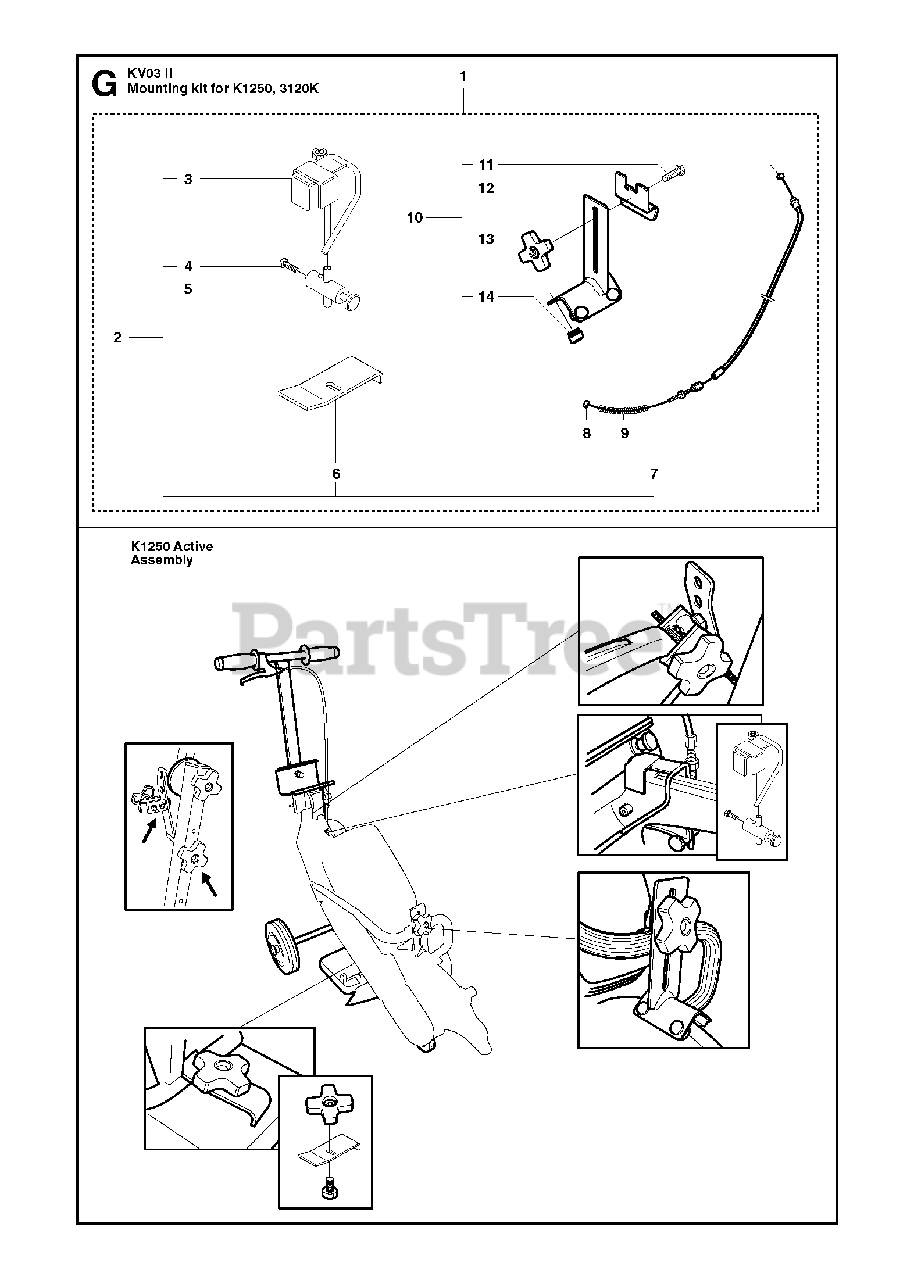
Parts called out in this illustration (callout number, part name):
1	CUTTING TROLLEYK1250. Incl. 2, 10
1	ATTACHMENT KIT3120K. Incl. 2, 10
6	PRESSURE PLATEK1250
7	THROTTLE WIREIncl. 8, 9
10	RETAINERK1250. Incl. 11 - 14
10	RETAINER3120K. Incl. 11 - 14
13	STEERING WHEEL
